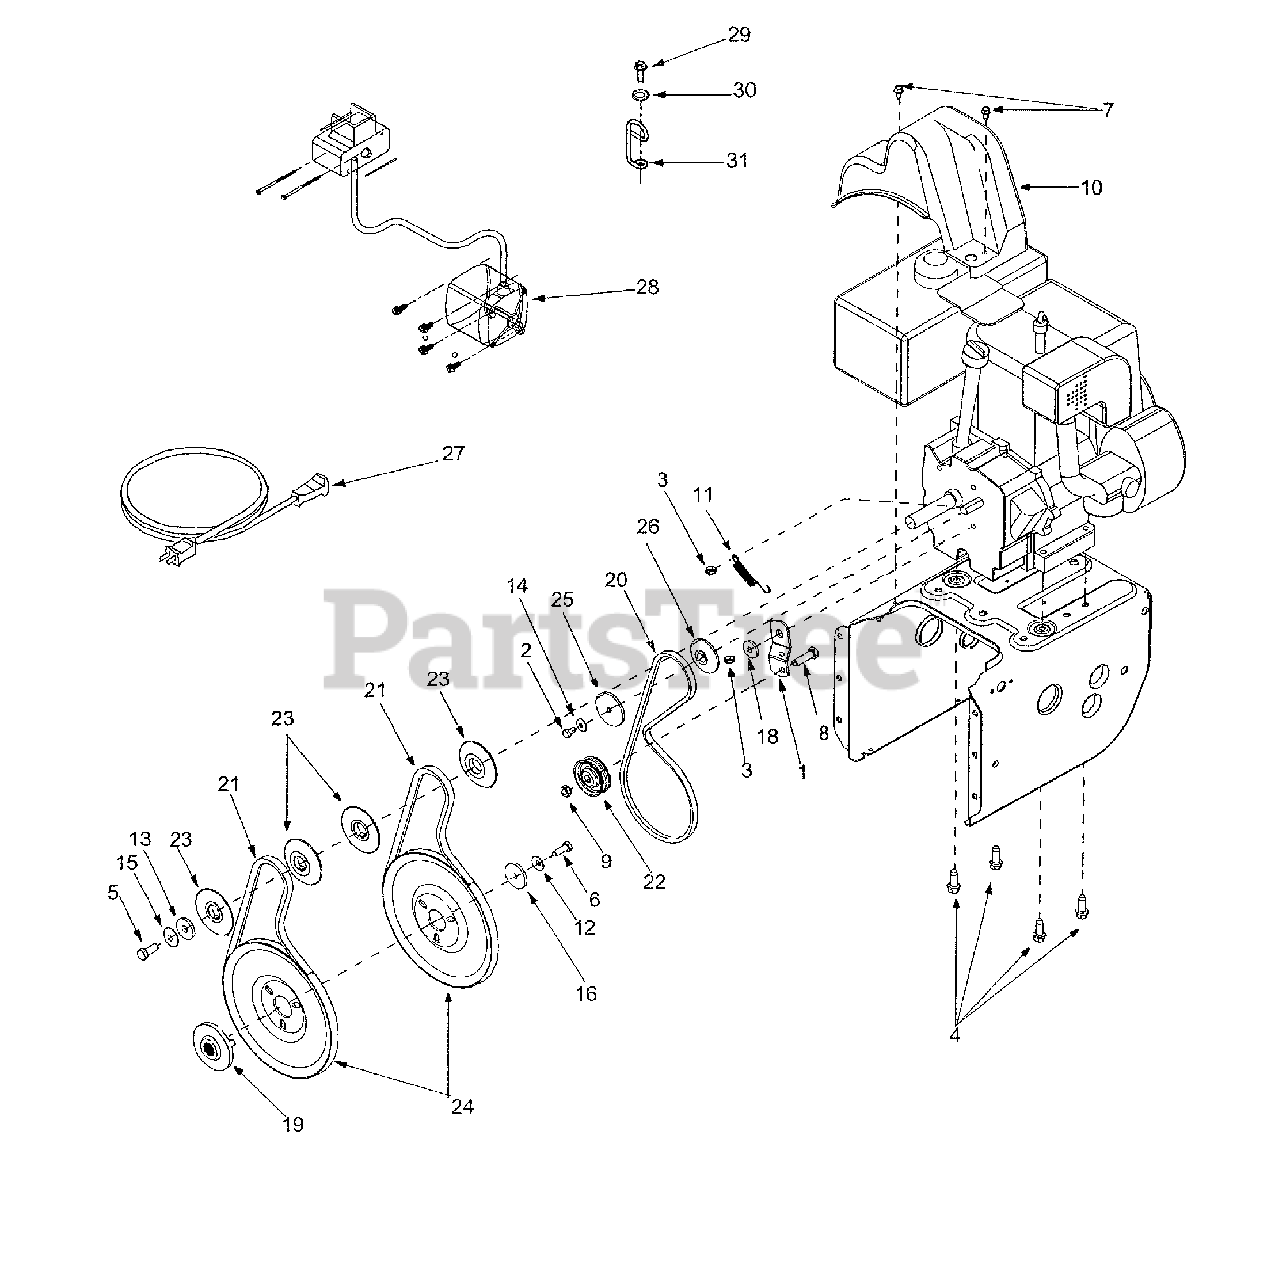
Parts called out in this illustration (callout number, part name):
3	Hex Scr wl Patch: 5/16-24 x 0.75"
4	Hex Washer Head Sems Screw
5	Hex Bolt 3/8-24 x .875" Gr.8
6	Hex Scr w/ Patch: 5/16-24 x .875"
7	Hex Washer Head TT
8	Hex Screw: 3/8-16 x 1.0"
9	Top Lock Jam Nut: 3/8-16
10	Belt Cover
11	Extension Spring
12	Bellevile Washer
13	Flat Washer
14	Bell Washer
15	Bell Washer
16	Flat Washer
18	Shoulder Spacer
19	Adapter Pulley
20	V-Belt
21	Belt
22	Flat Idler
23	Pulley Half
24	Auger Pulley
25	Pulley Half
26	Pulley Half
27	Extension Cord
28	Electric Start Kit
29	Lock Nut 114-20
30	Flat Washer.28 ID x .74 OD
31	Cable Guide
